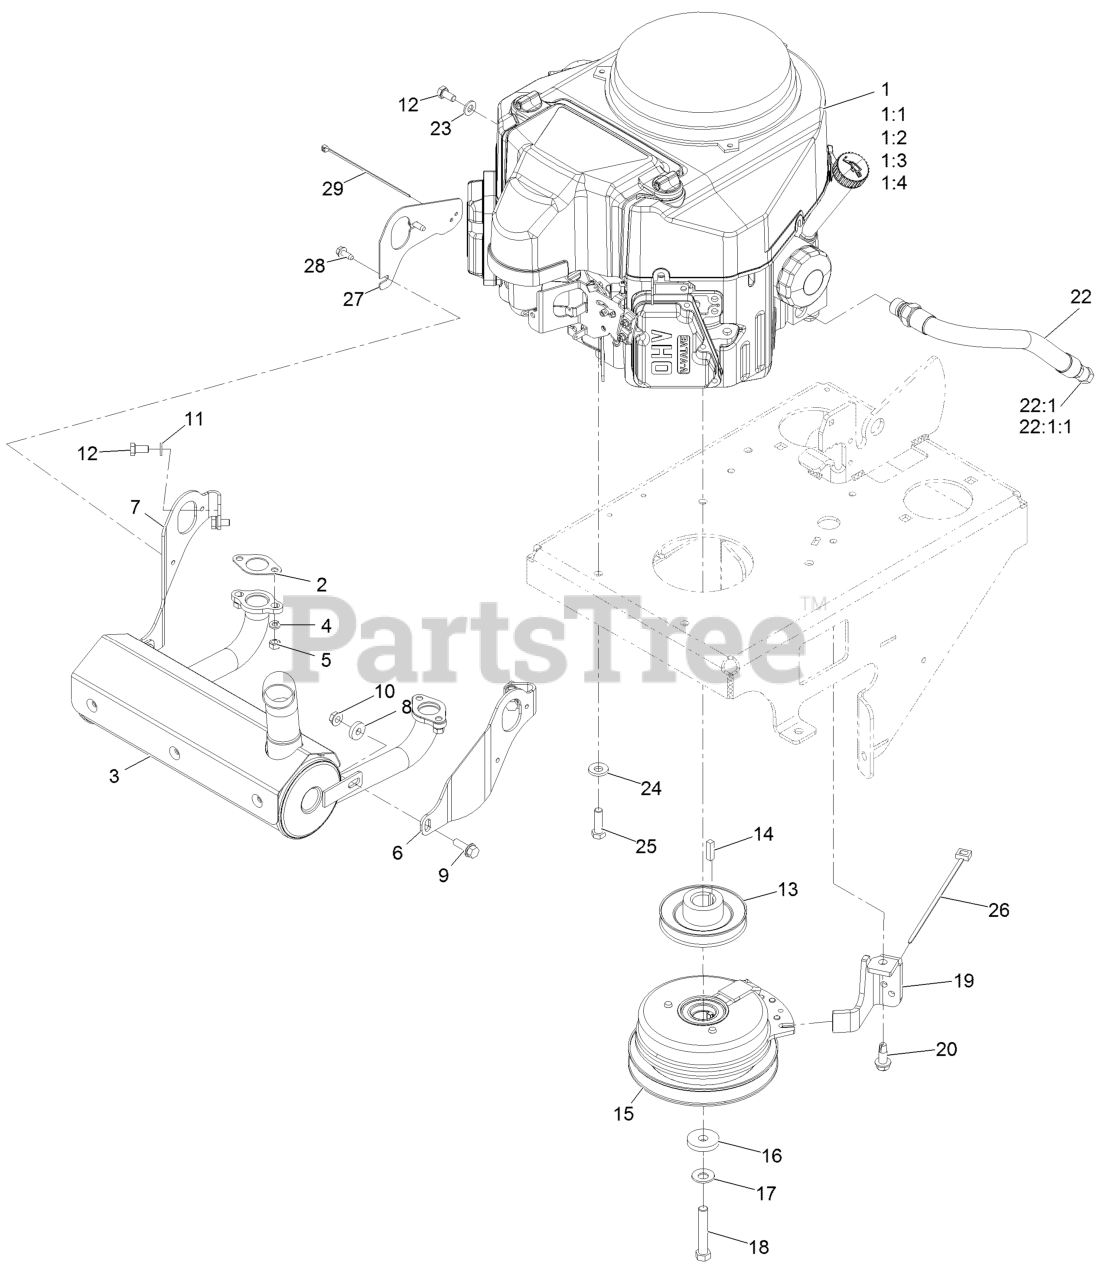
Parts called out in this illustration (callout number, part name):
2	GASKET-EXHAUST
4	WASHER-LOCK
6	BRACKET-MUFFLER MOUNT, LH
7	BRACKET-MUFFLER MOUNT, RH
9	SCREW-HHF
11	WASHER-LOCK
12	SCREW-HH
13	PULLEY
15	CLUTCH-175 FT-LB
16	WASHER
17	WASHER-SPRING
18	SCREW-HH
19	ANCHOR-CLUTCH
20	SCREW-TAPPING
22	ENGINE OIL DRAIN HOSE ASM
22:1	PLUG-HH
22:1:1	O-RING
23	WASHER-PLAIN
24	WASHER-BELLEVILLE
25	SCREW-HH
26	TIE-CABLE
27	GUARD-CABLE, SPARK PLUG
28	SCREW-HWH
29	TIE-CABLE
